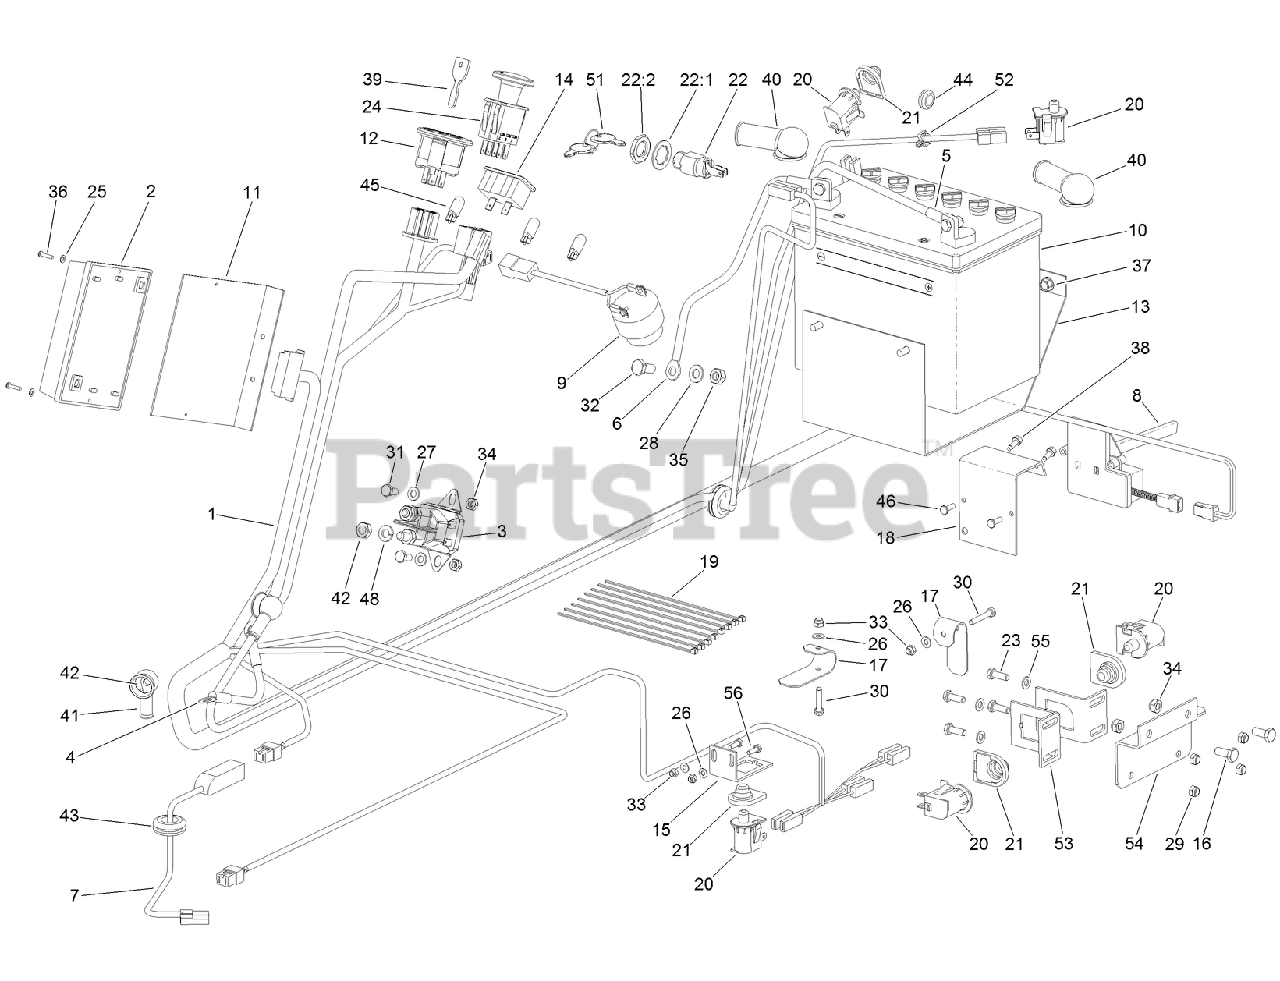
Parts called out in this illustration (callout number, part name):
1	HARNESS-WIRING
2	CONTROL MODULE
3	SOLENOID
4	CABLE-STARTER
5	CABLE-BATTERY, POSITIVE
6	CABLE-BATTERY, NEGATIVE
7	HARNESS-CLUTCH
8	OVERLOAD SWITCH ASM
9	BUZZER
10	BATTERY-12V
11	BRACKET-SUPPORT, MODULE
12	SWITCH-IGNITION
13	HOLDER-BATTERY
14	HOURMETER
15	HOLDER
17	LEVER-SPRING
18	BRACKET-SWITCH
19	TIE-CABLE
20	SWITCH-DELTA
21	COVER-PROTECTIVE
22	STARTER SWITCH ASM
22:1	WASHER-LOCK
22:2	NUT-HH
24	SWITCH-PTO
26	WASHER
27	WASHER
28	WASHER-PLAIN
29	NUT-LOCK
30	SCREW-HEX
31	SCREW-HH
32	SCREW-HH
33	NUT-HEX
34	NUT-LOCK
35	NUT-LOCK, NI
38	SCREW-TAP
39	KEY-IGNITION
40	BOOT-RUBBER
41	BOOT-RUBBER
42	NUT-HHF
43	BUSHING
44	BUSHING
48	WASHER-SPRING
51	KEY-IGNITION
52	CLIP-SNAP
53	HOLDER-SWITCH
54	HOLDER-SWITCH
55	WASHER
